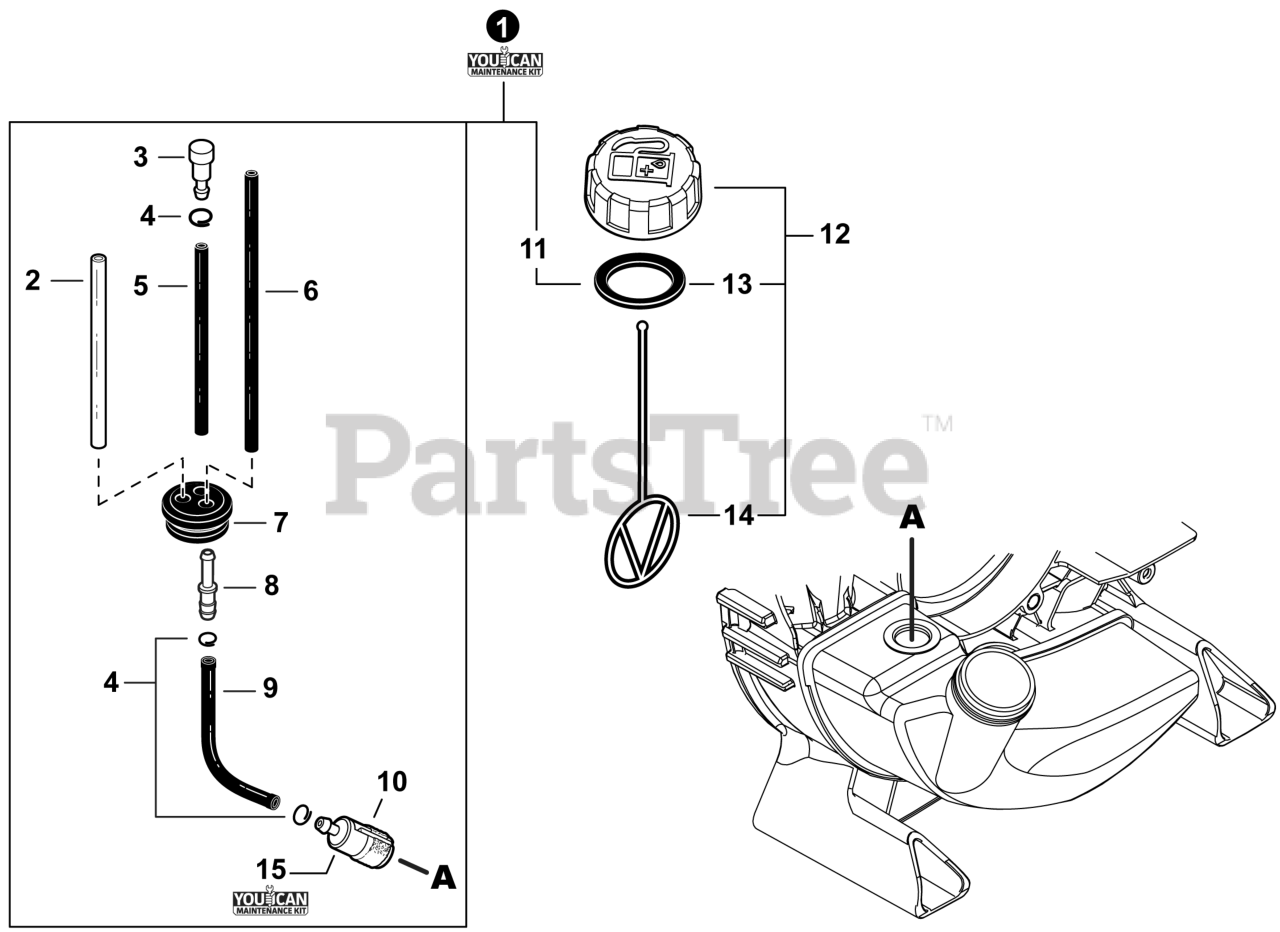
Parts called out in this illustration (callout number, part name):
1	FUEL SYSTEM KIT - YOUCANT
2	PIPE, FUEL 3x6x85 YELLOW
3	VENT ASSY
5	PIPE, FUEL 3x5x60 BLACK
6	PIPE, FUEL 3x5.5x80 BLACK
7	GROMMET, FUEL 5
8	CONNECTOR, PIPE 5x3.5
9	PIPE, FUEL 3x5x140 BLACK
10	FILTER, FUEL
11	GASKET, FUEL CAP
12	CAP ASSY, FUEL
13	GASKET, FUEL CAP
14	CONNECTOR, CAP L= 100 MM
15	TUNE-UP KIT - YOUCANT
